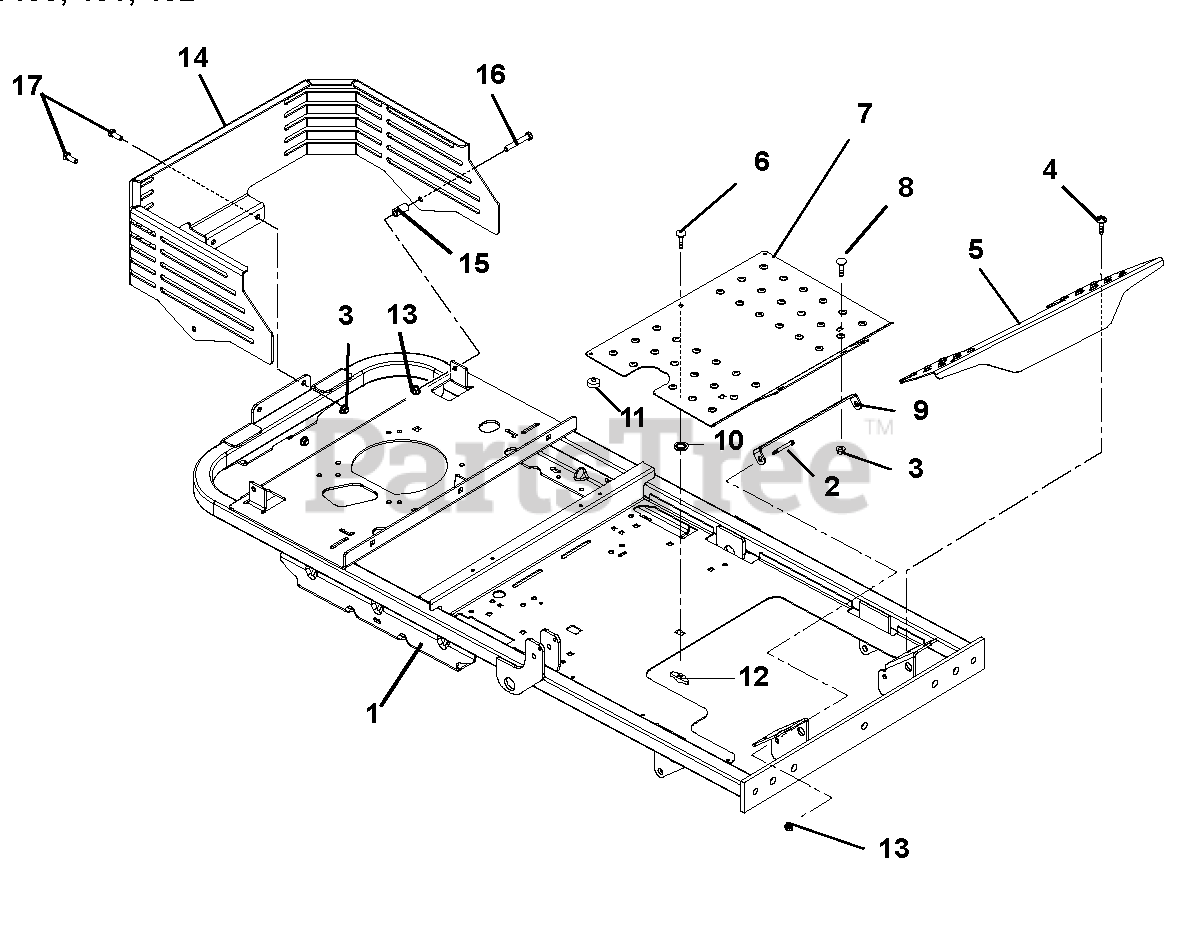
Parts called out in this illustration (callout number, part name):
1	Weldment, Frame
2	Bolt, Shoulder .375-16 x .62
3	Nut, .38-16 Flange Nyloc
4	Screw, Tap .31-18 x .50
5	Foot Rest
6	Bolt, Round Head Square Neck .31-18 x 1.00 Grade 5
7	Plate, Deck Access
8	Bolt, Round Head Square Neck .38-16 x 1.00 Grade 5
9	Bracket, Deck Access
10	Nut, Push .312
11	Grommet, Bumper
12	Knob, Wing .312-18
13	Nut-Locking-Top-Flange .31-16
14	Engine Guard, EVERRIDE XL
15	Bushing, Spacer .390 x .625 x 1.25 Promaster
16	Bolt, Hex .38-16 x 2.50 Grade 5
17	Bolt, Hex .38-16 x 1.00 Grade 5
